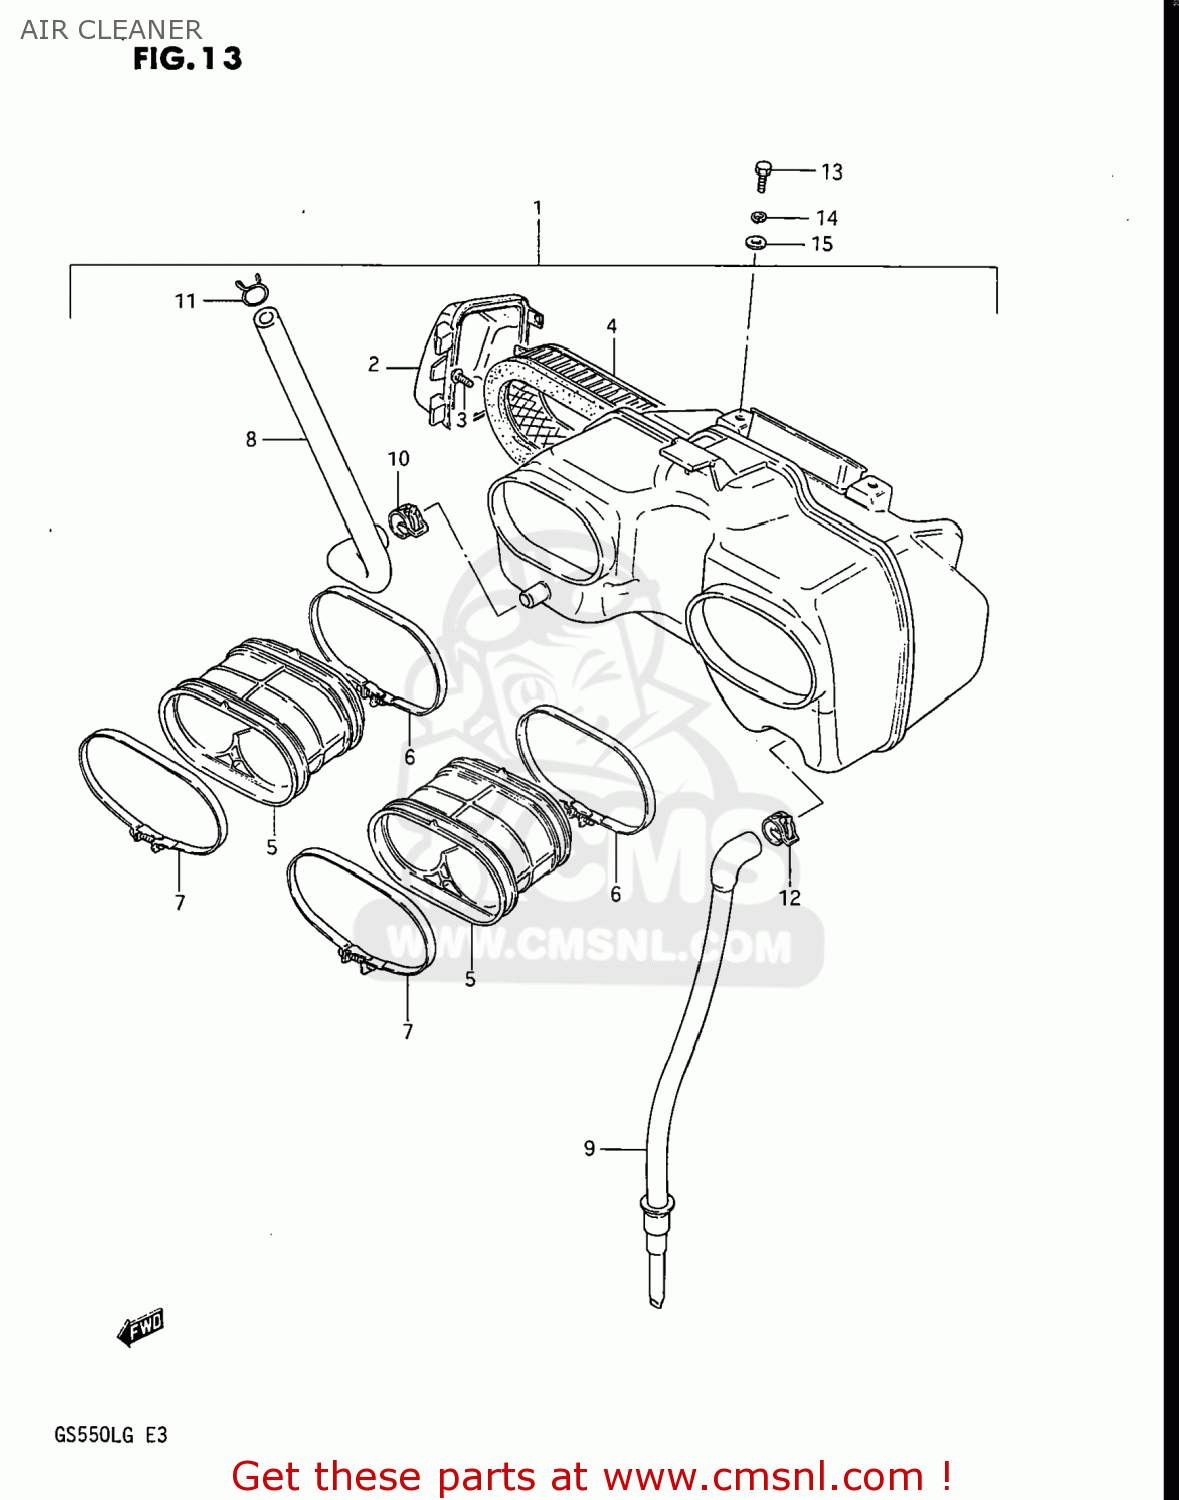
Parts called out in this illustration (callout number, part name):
1	CLEANER ASSEMBLY,AIR
2	CAP,AIR CLEANER
3	SCREW M5X12 DIN 7985/N
4	FILTER,AIR CLEANER
5	TUBE,AIR CLEANER OUTLET
6	CLAMP,AIR CLEANER
7	CLAMP,CARBURETOR SIDE
8	TUBE,BREATHER
9	DRAIN TUBE
10	CLIP
11	CLIP,BREATHER TUBE
12	CLIP
13	BOLT, UPPER
14	LOCK WASHER
15	WASHER
